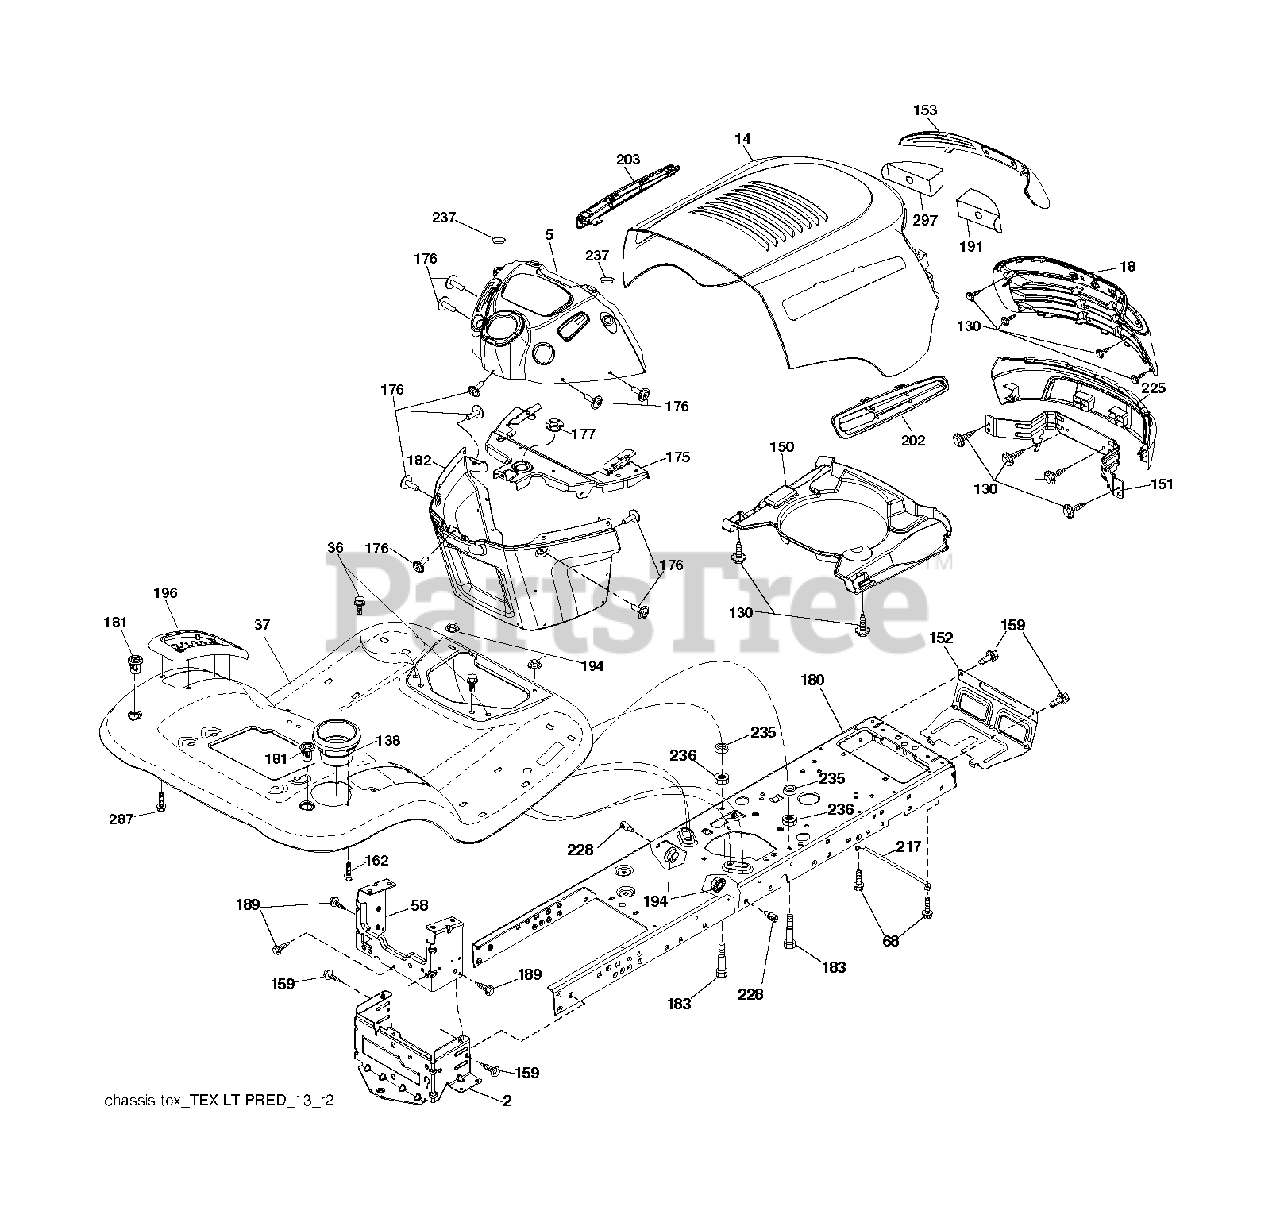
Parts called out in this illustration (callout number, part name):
2	DRAWBAR.LOWER.2PC.18/22
36	SCREW 5/16"
58	DRAWBAR UPPER 2PC SMALL FENDER
130	SCREW.#10 X 0.750.BOS THREAD
138	CUPHOLDER.TL.TEX.BLACK
151	BRACKET.PIVOT.ALPHA.LT
152	SHIELD.BROWNING/DEBRIS
159	SCREW, 3/8-16X3/4
162	SCREW.HI-LO.CONSOLE
175	CROSSMEMBER
176	SCREW.#10-24X5/8.RN.QU
177	BUSHING STEERING
180	CHASSIS.STAMPING.LT/GT
181	FEND/FTRST.PCH.CPH.NFW
182	DASH.LWER.PREDATOR/HUSQ.LT
183	BOLT.5/16-18X1-1/4 FULL.THREAD
189	SCREW
191	INSERT.REFLECT.PREDATOR.LT.RH
194	NUT LOCK HEX FLANGE 5/16-18
196	CONSOLE.ASM.DECKLFT.BL/RBT.TLT
217	ROD.PIVOT.HOOD
228	STUD.FASTNER.W/ANTI-ROTATE
235	SPACER FENDER
236	NUT.CENTERLOCK.5/16-
237	PLUG.MOUNT.CARGO.BLK
297	REFLECTOR.INSERT.PRED.LH.LT
